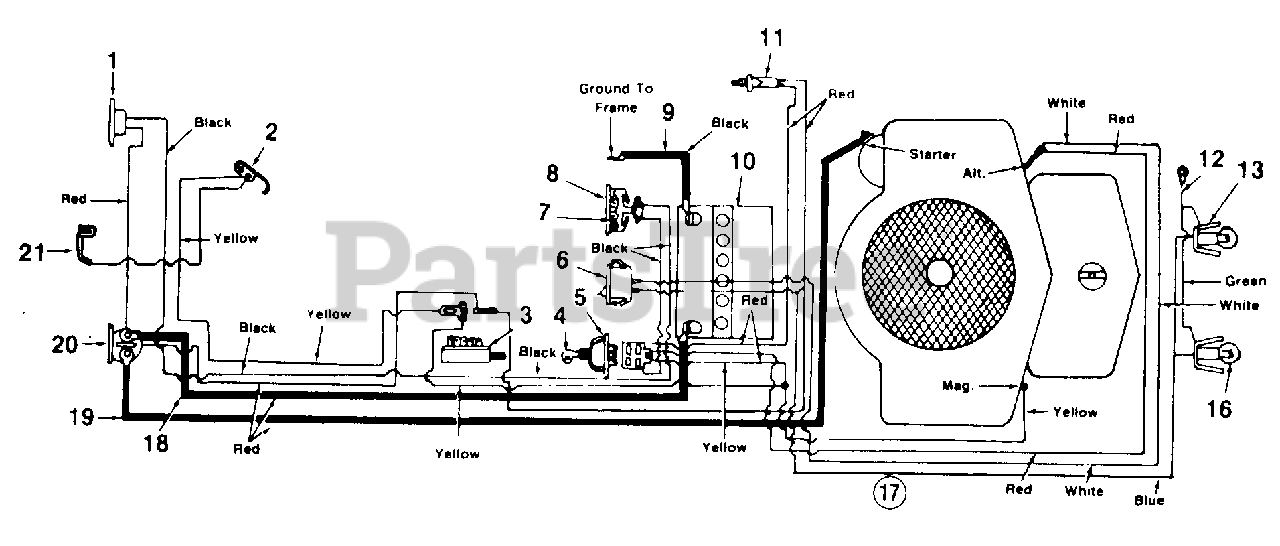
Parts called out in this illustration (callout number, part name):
1	Circuit Breaker
2	Spring Switch
3	Safety Switch
4	Ignition Key
5	Ignition Switch
6	Headlight Switch
7	Foam Strip
8	Ammeter
9	Ground Wire 14.0" Lg.
10	12 Volt Battery
11	Safety Switch
12	Ground Wire
13	Socket
16	Lamp
17	Wire Harness
18	Electric Wire 27.0" Lg.
19	Electric Wire 32.5" Lg.
20	Solenoid
21	Spring Switch
